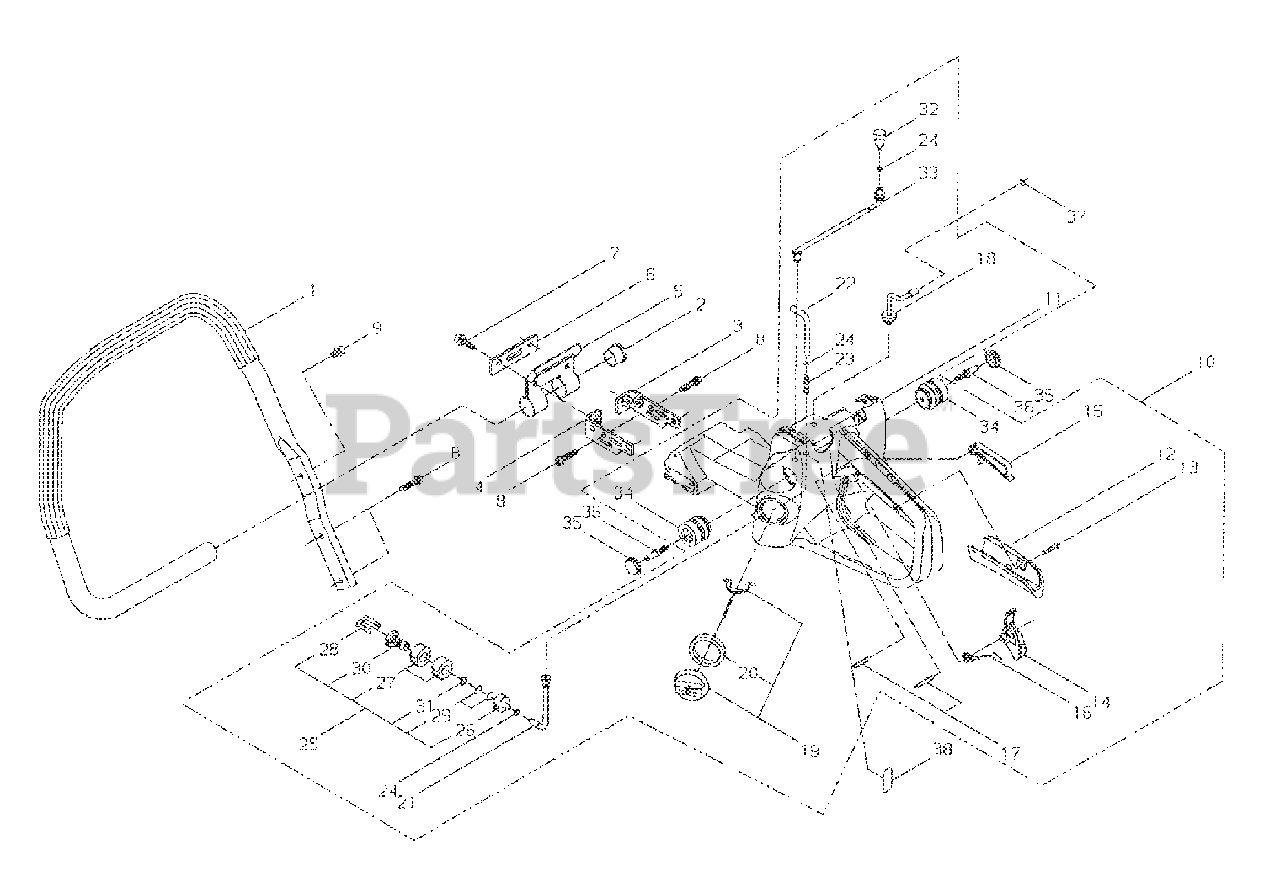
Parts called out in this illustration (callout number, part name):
1	HANDLE - FRONT
2	CAP
3	STAY - RIGHT
4	STAY - LEFT
5	BRACKET
6	PLATE
7	SCREW - 5X20
8	BOLT
9	SCREW - 5X10
10	HANDLE ASSY - REAR
11	HANDLE - REAR
12	GRIP - LOWER
13	SCREW - 4X20 -- TAPPING
14	TRIGGER, THROTTLE
15	LEVER, TRIGGER LOCKOUT
16	SPRING, LEVER
17	PIN - 4X25
18	TUBE
19	CAP ASSY
20	GASKET, CAP
21	TUBE
22	TUBE
23	CONNECTOR, PIPE
24	RING, RETAINING - 6
25	FUEL FILTER ASSY
26	WEIGHT, FUEL FILTER
27	FILTER, FUEL
28	CLIP, FILTER
29	SCREEN, FILTER
30	CASE, FILTER
31	RING, RETAINING
32	VALVE
33	TUBE
34	CUSHION
35	PLUG
36	BOLT, LIMITER
37	RING, RETAINING - 6
38	LABEL - INSTRUCTION
